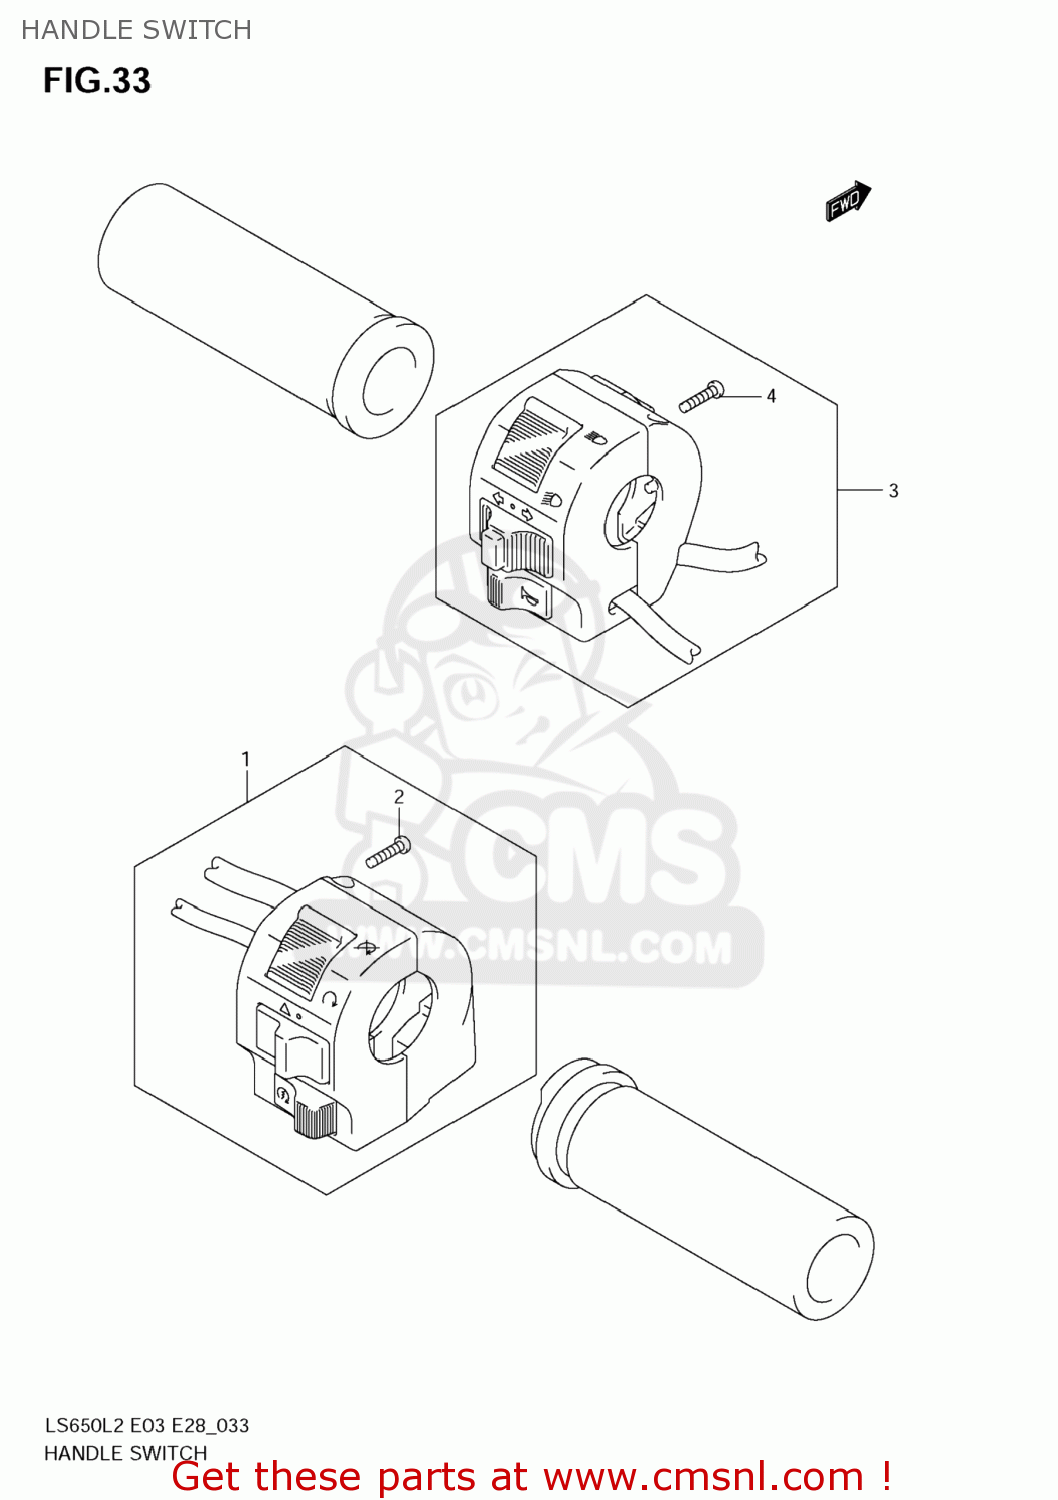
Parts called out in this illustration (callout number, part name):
1	SWITCH ASSY,HANDLE,R
2	SCREW
3	SWITCH ASSY,HANDLE,L
4	SCREW
